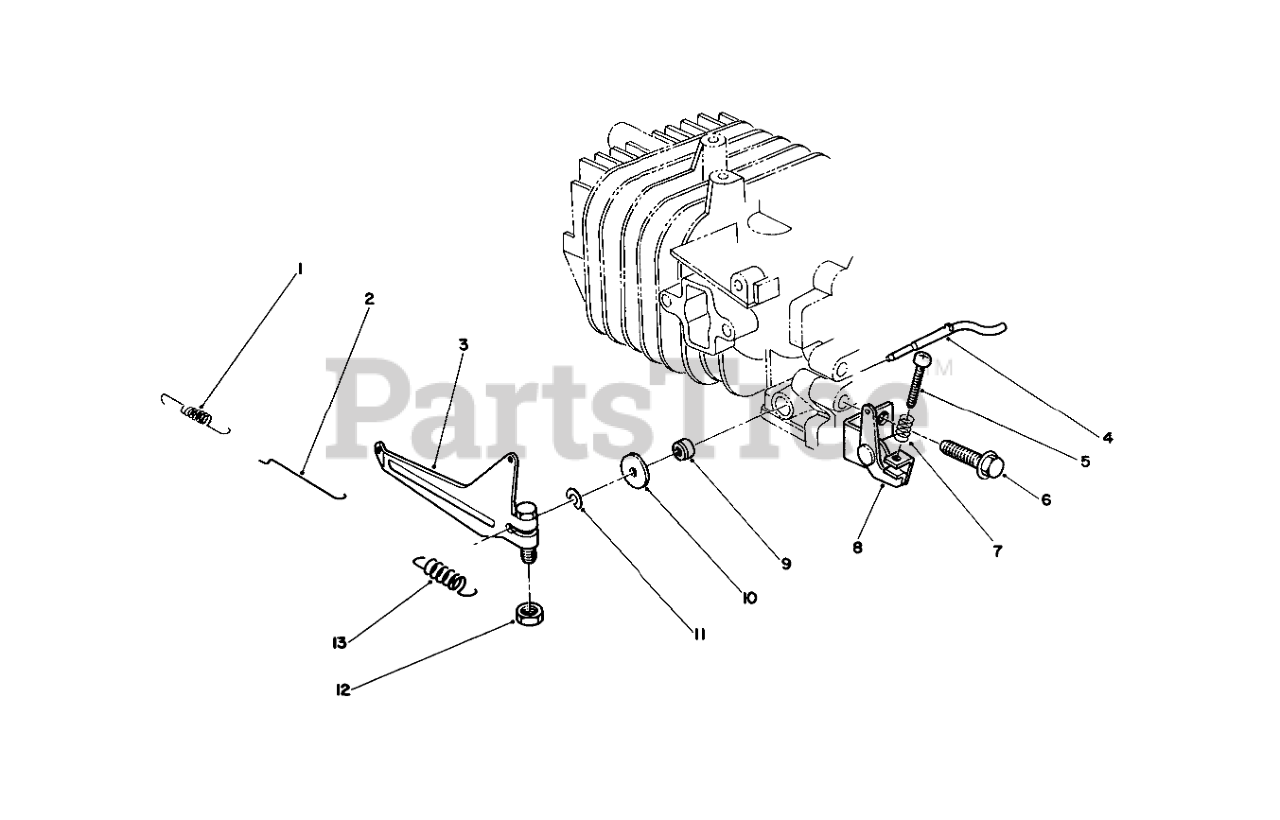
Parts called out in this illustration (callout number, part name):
1	CARB SPRING
2	CARB ROD
3	GOV ARM
4	SHAFT
5	SCREW
7	SPRING
8	GOV SPR BRKT
9	SEAL-OIL
10	WASHER
11	E-RING
13	GOV SPRING
